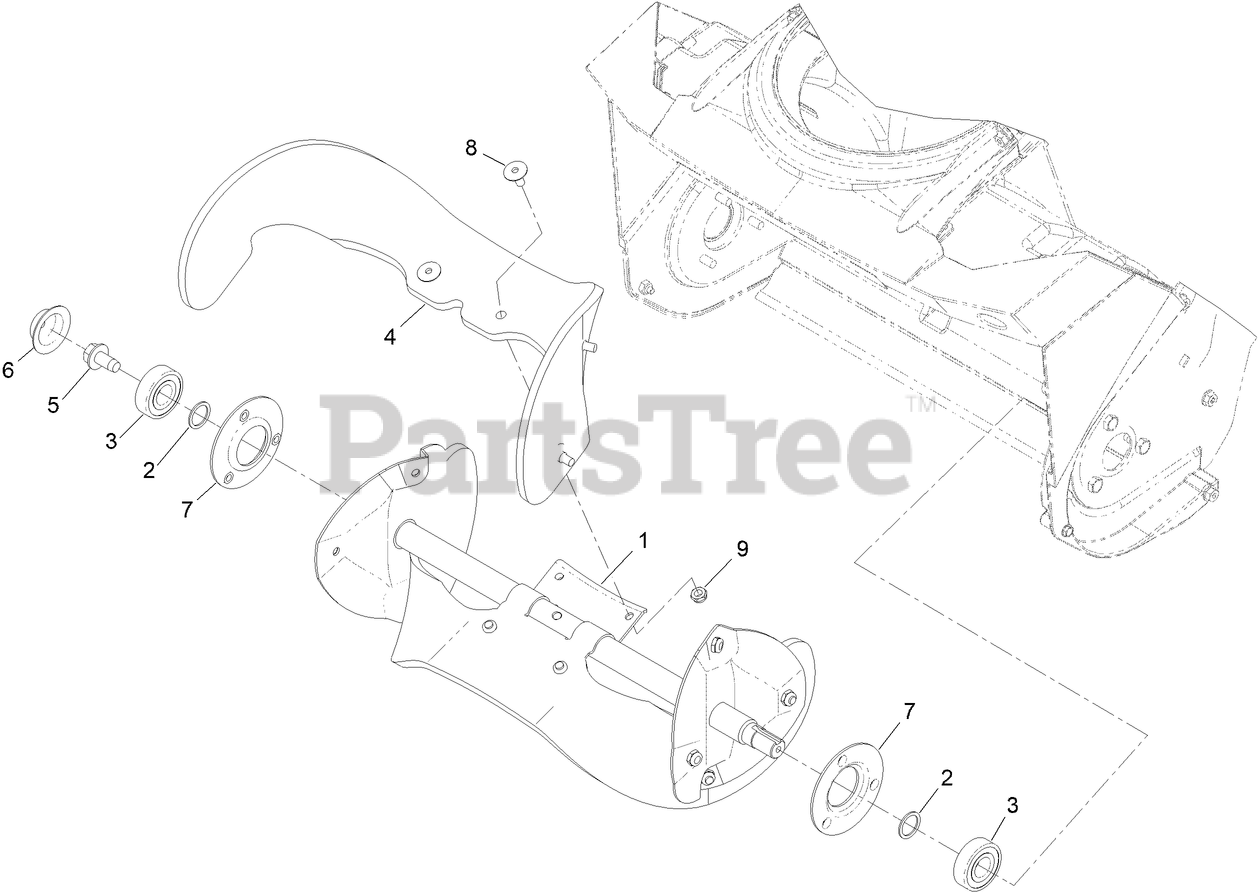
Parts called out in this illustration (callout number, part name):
1	ROTOR ASM
2	WASHER-THRUST
3	BEARING-BALL
4	BLADE-ROTOR
5	SCREW-HWH
6	CAP-SIDEPLATE, RH
7	FLANGE-BEARING
8	SCREW-COUNTERSUNK, OVAL
9	NUT-HEX
